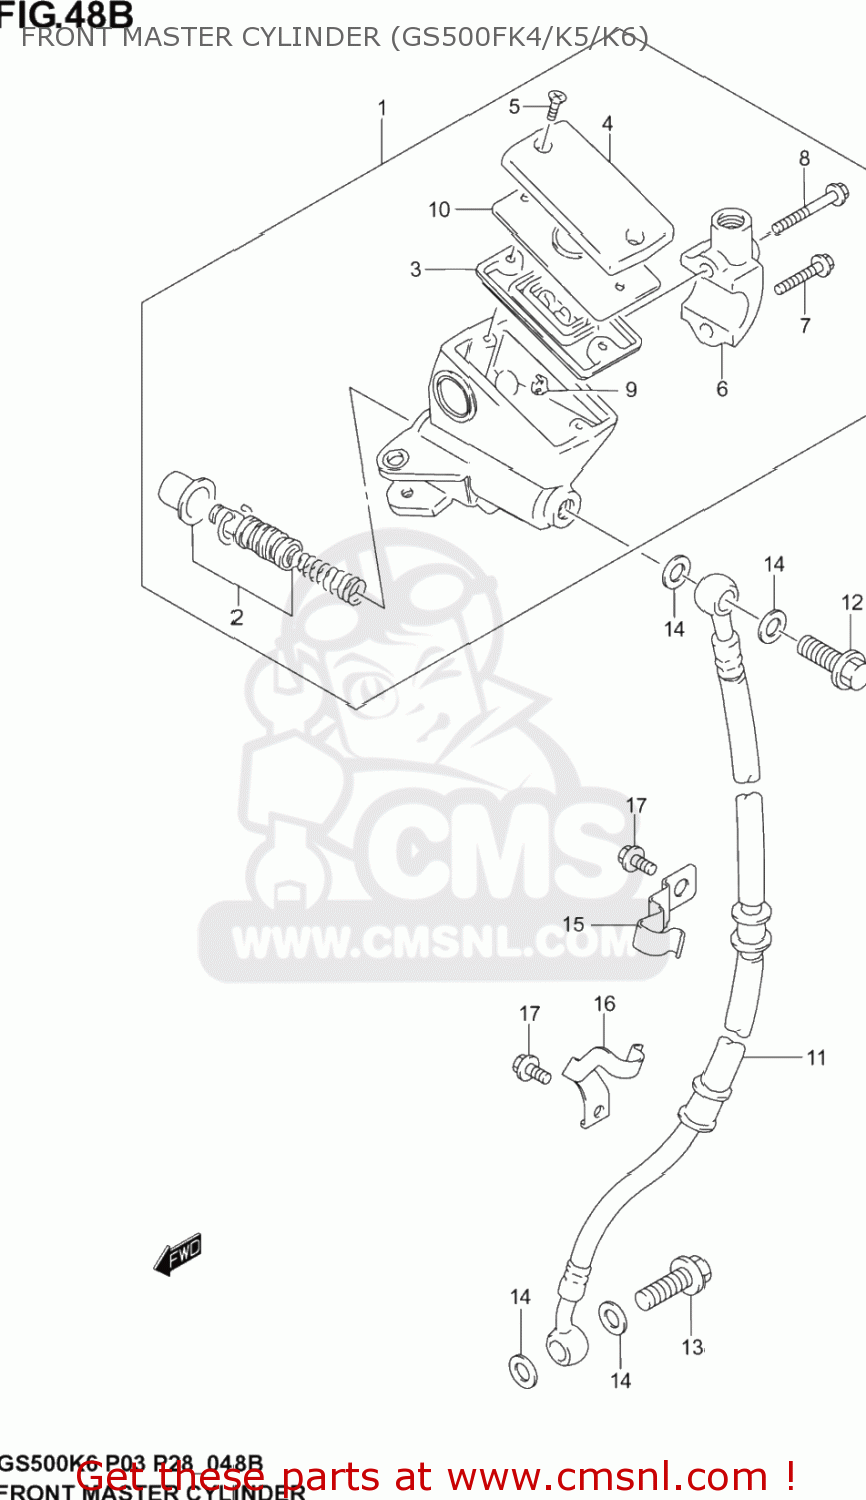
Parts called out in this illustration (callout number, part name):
1	CYLINDER ASSY
2	PISTON/CUP SET
3	DIAPHRAGM
4	CAP
5	SCREW
6	HOLDER
7	BOLT
8	BOLT UPPER
9	PROTECTOR
10	PLATE
11	HOSE, FR BRAKE
12	BOLT UNION
13	BOLT UNION
14	WASHER
15	CLAMP, HOSE
16	CLAMP, HOSE
17	BOLT OIL LEVEL
